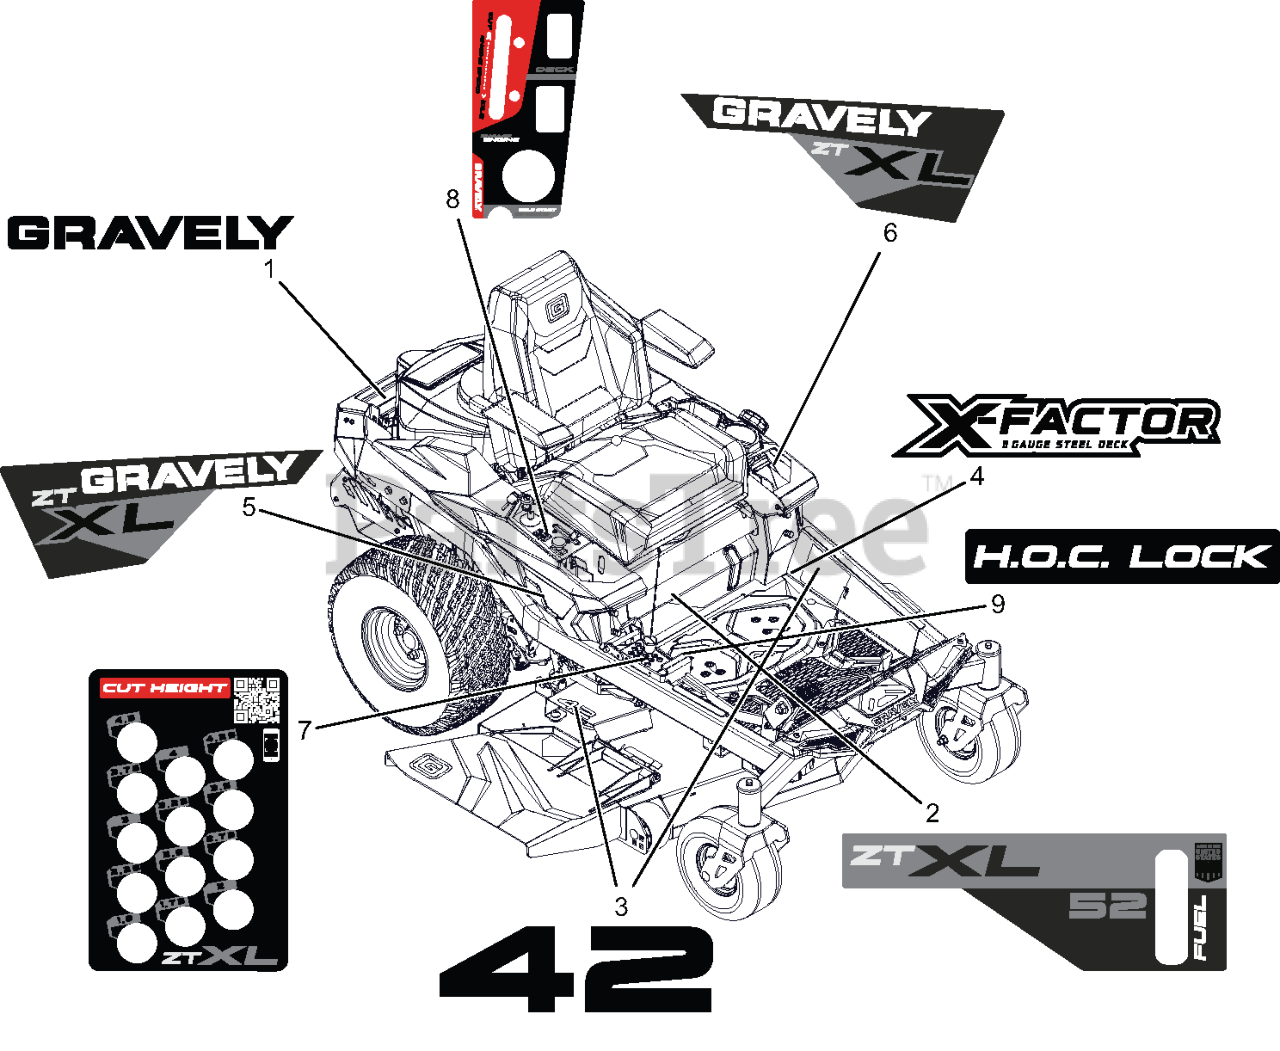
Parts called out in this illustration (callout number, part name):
1	DECAL- GRAVELY
2	DECAL- ZTXL 42-KICK PLATE
3	DECAL- DECK 42"
4	DECAL- DECK X-FACTOR
5	DECAL- ZT XL FENDER RH
6	DECAL- ZT XL FENDER LH
7	DECAL- HEIGHT OF CUT-XL
8	DECAL- CONTROL PANEL-GRAVELY
9	DECAL- HOC LOCK
